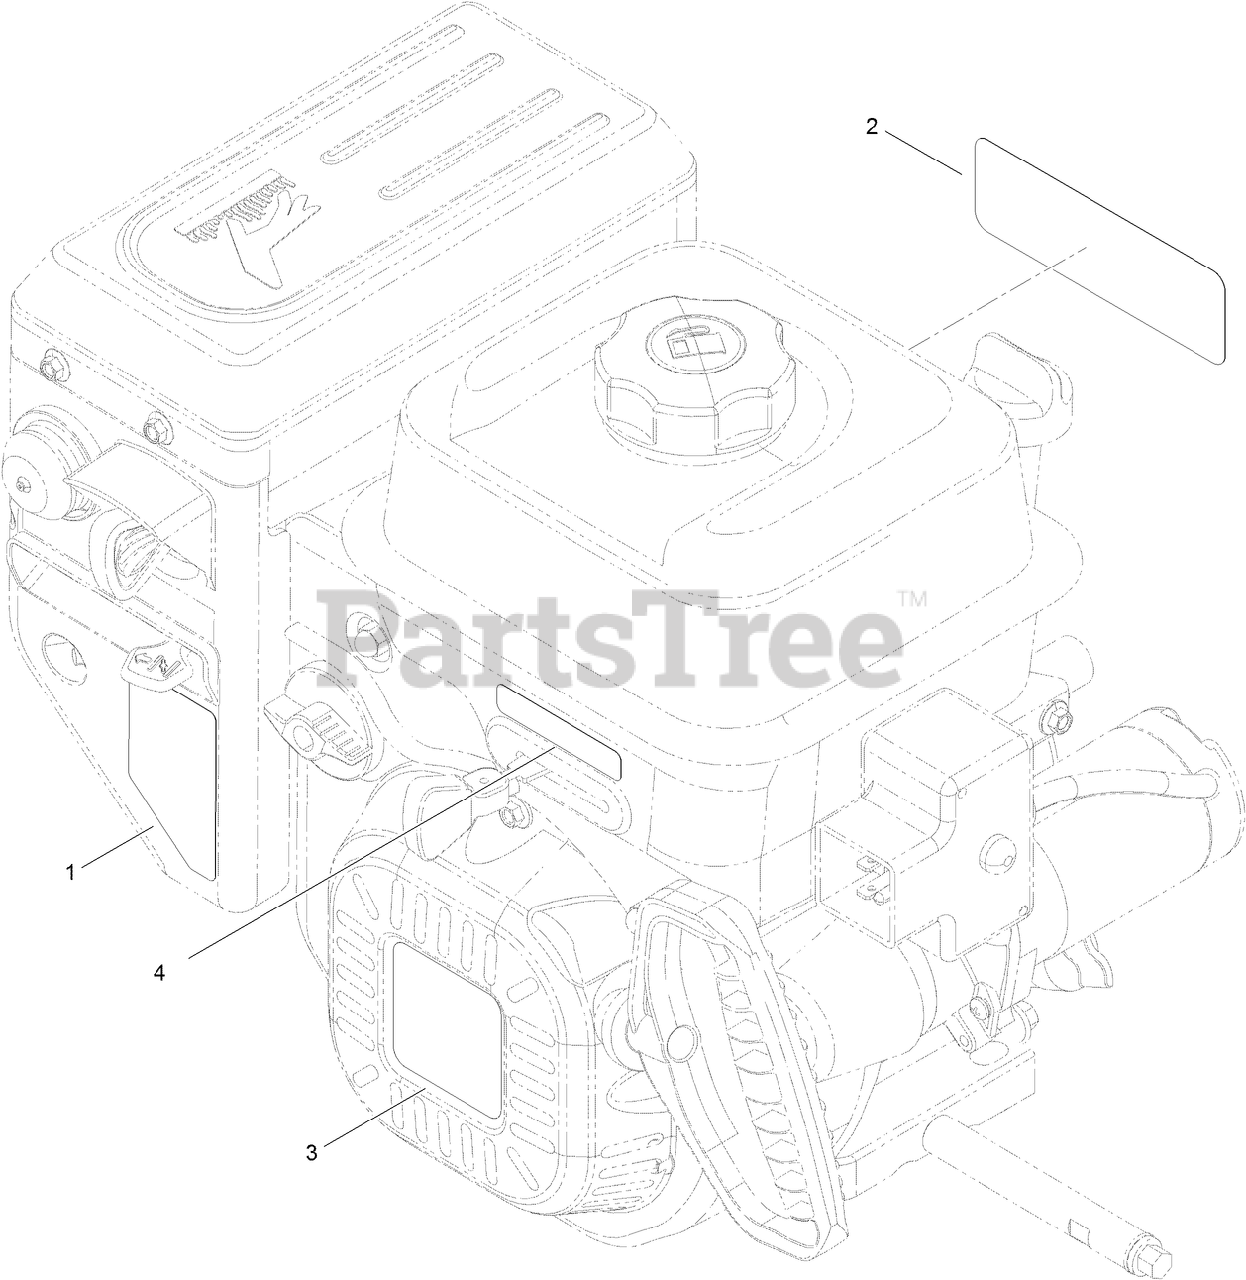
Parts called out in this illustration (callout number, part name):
1	DECAL-CONTROL, ENGINE
2	DECAL-ENGINE SERIES, G250
3	DECAL-RECOIL, G250
4	DECAL-THROTTLE
